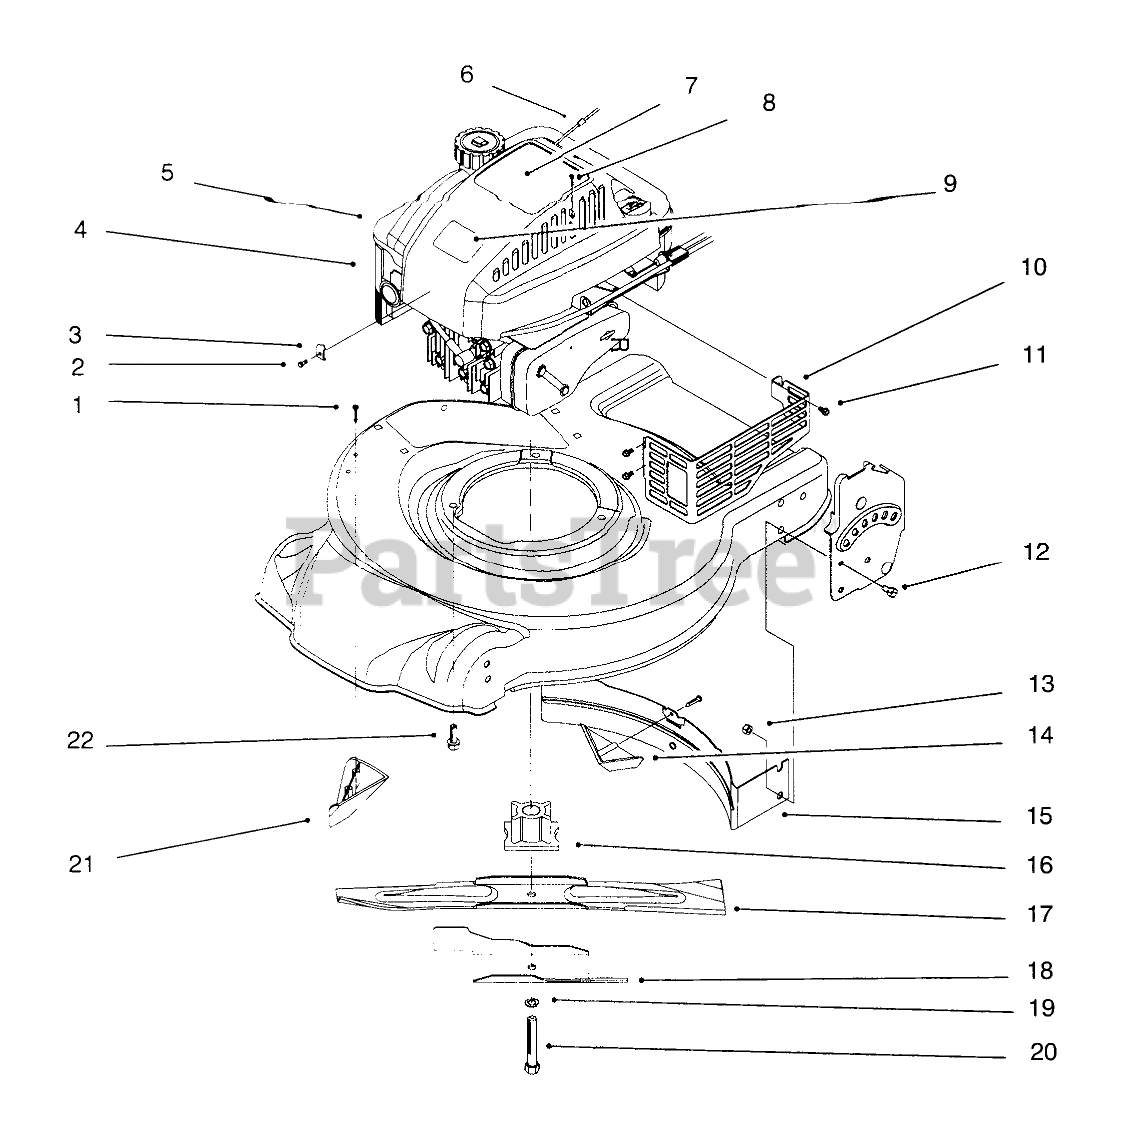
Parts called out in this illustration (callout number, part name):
1	SCREW-PPH
2	SCREW-CLAMP
3	CLAMP-CASING
5	SHROUD-ENGINE
6	STOP-ROPE
7	OBS EXCEPT FOR SERVICE DECAL - ENGINE
8	SCREW-PPH
9	PLATE-LOGO
10	SHIELD-MUFFLER
11	SCREW-HWH
12	SCREW-HH
13	NUT-LOCK, NI
14	KICKER-REAR
15	Baffle-Rear
16	BLADE RETAINER
17	Blade
18	Accelerator
19	WASHER-LOCK
20	SCREW-BLADE
21	KICKER - SIDE
22	SCREW-HWH
